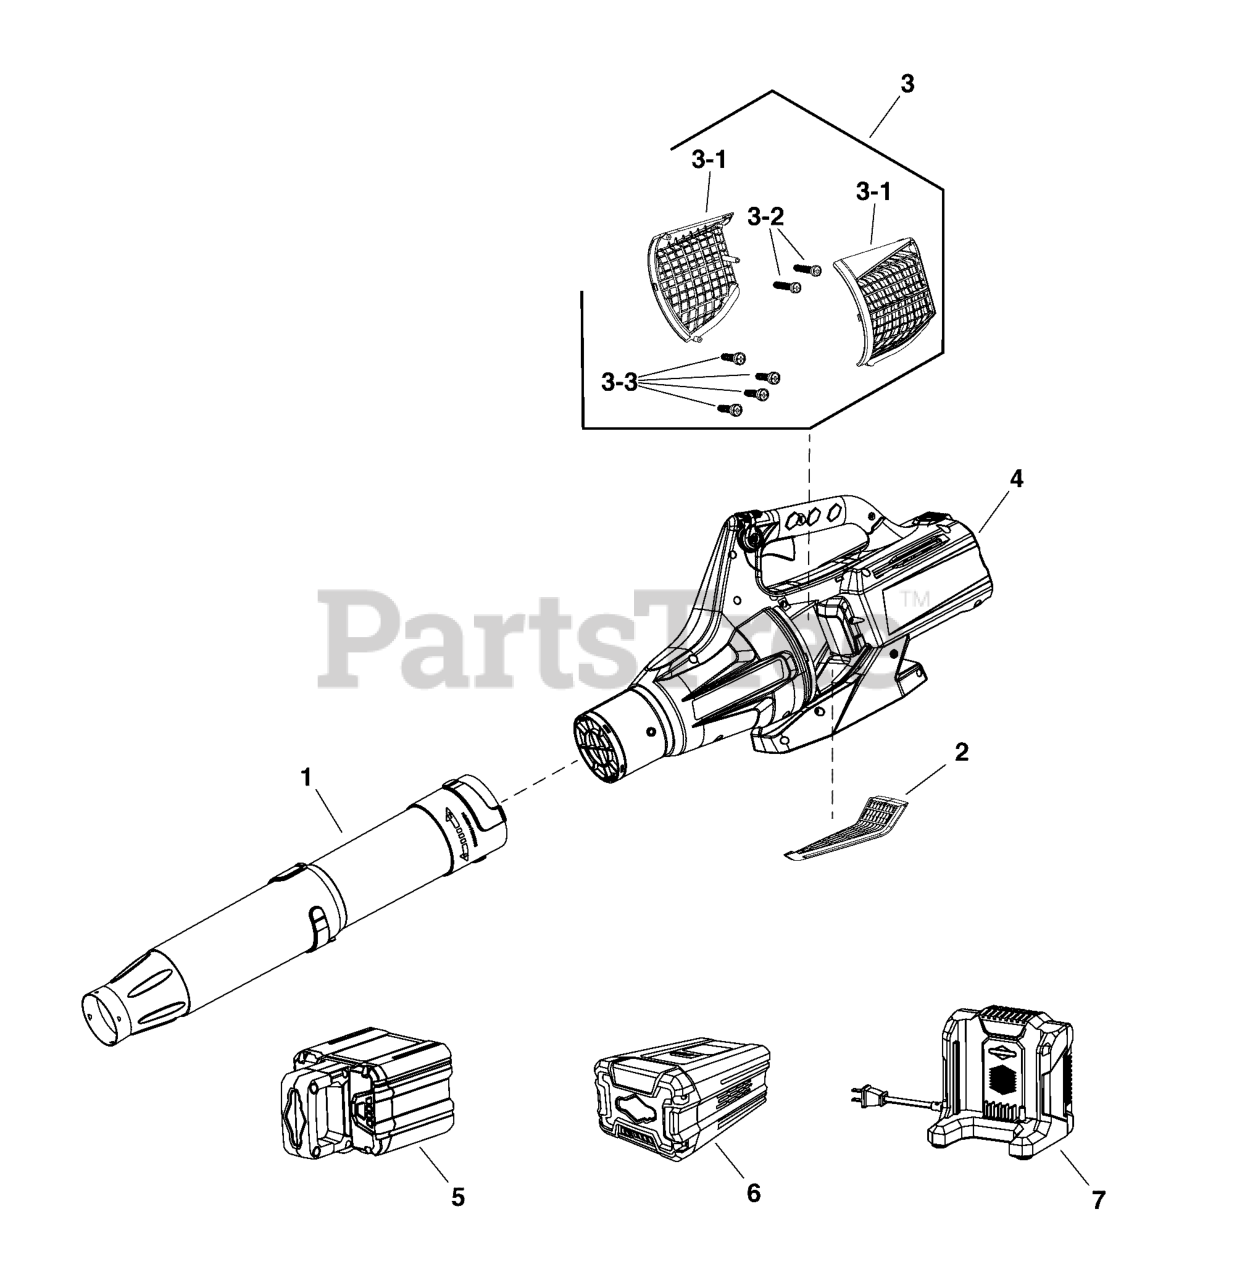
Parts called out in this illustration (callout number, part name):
1	TUBE ASSEMBLY
2	INLET GUARD ASSEMBLY
3	CENTER INLET GUARD ASSEMBLY
3-1	GUARD, INLET
3-2	SCREW
3-3	SCREW
4	* BLOWER, 48V
5	* BATTERY, 2.0, 48V
6	* BATTERY, 5.0, 48V
7	* BATTERY CHARGER, 48V
